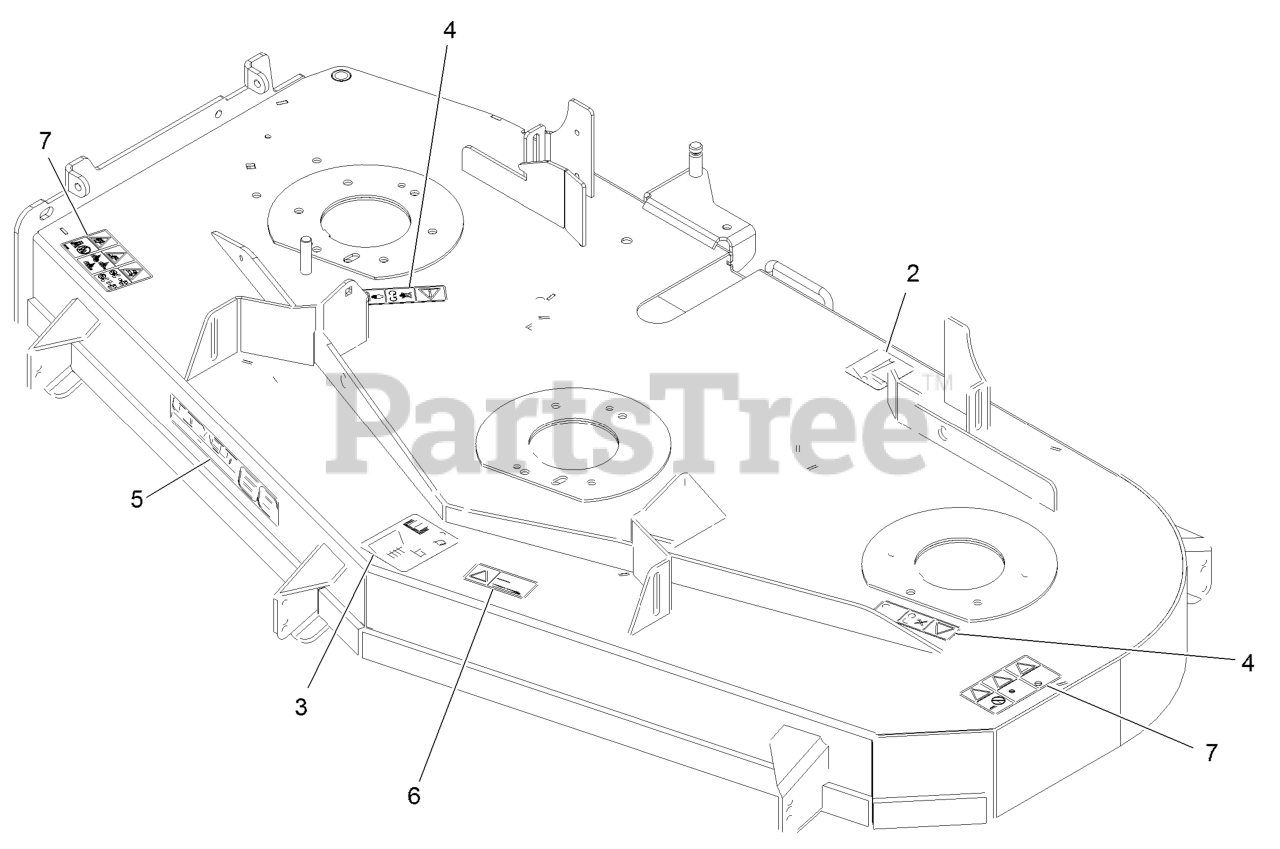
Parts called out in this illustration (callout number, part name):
2	Decal-Routing, Belt
3	Decal-Roller, Anti-Scalp
4	Decal-Missing, Cover
5	Decal-Ultracut 60 Series 3
6	Decal-Bolt Torque
7	Decal-Danger Thrown Objects
